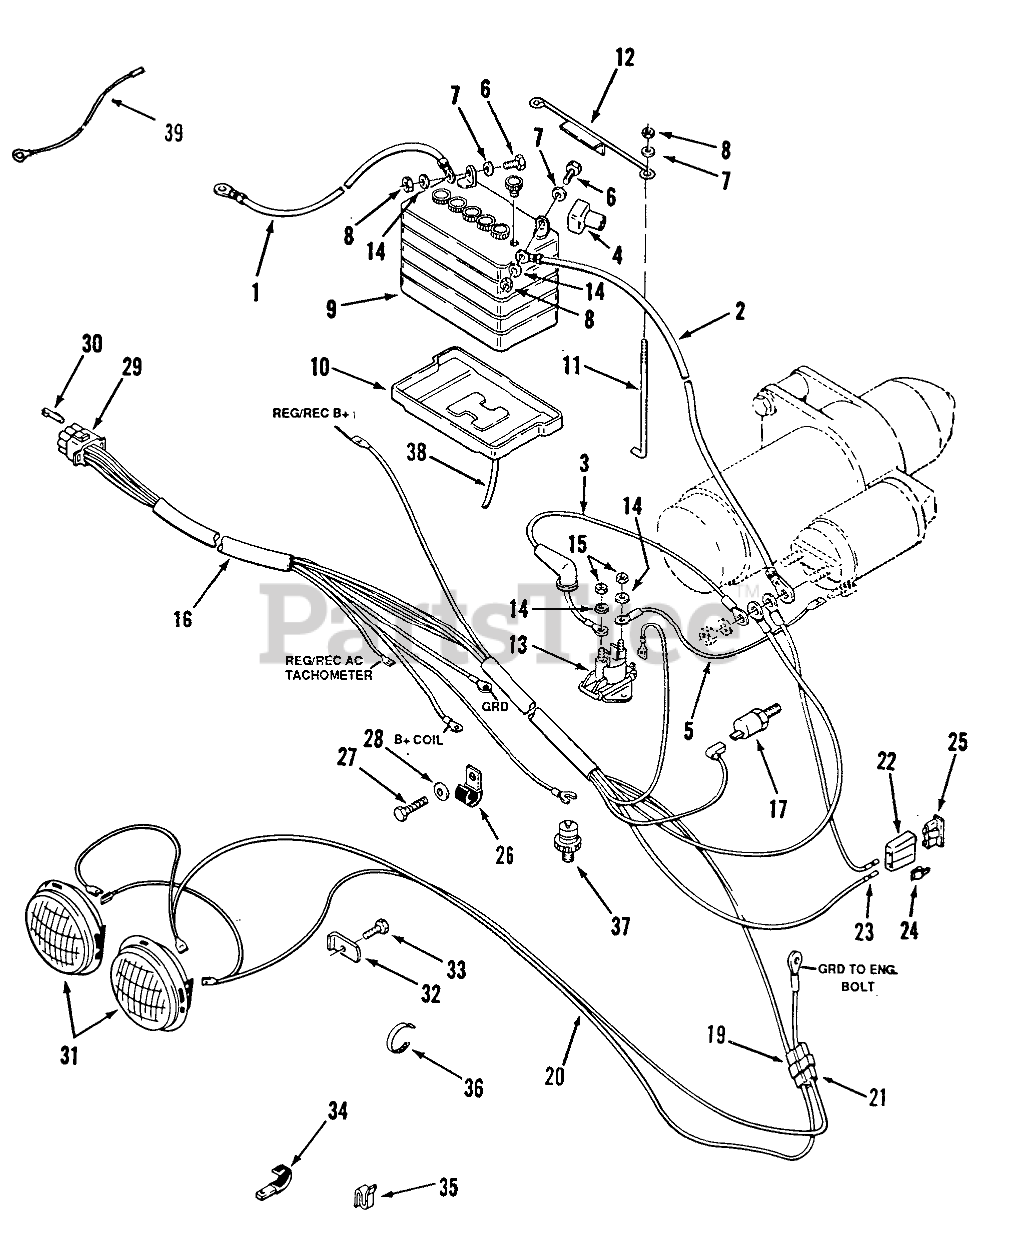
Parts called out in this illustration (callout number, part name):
1	ASS'Y-WIRE
2	ASS'Y-WIRE
3	ASS'Y-WIRE
4	Boot
5	ASS'Y-WIRE
6	Bolt
8	Nut
9	Battery
10	TRAY-BATTERY
11	HOOK-BATTERY RETAIN
12	HOLDDOWN-BATTERY
13	Solenoid
14	Washer
15	Nut
16	Engine Wiring Harness
17	HIGH TEMPERATURE
18	RECEPTACLE TERMINAL
19	MALE CONNECTOR
20	HARNESS-HEADLIGHT
21	CONNECTOR BODY
22	AUTO-FUSEBLOCK TERM
23	TERMINAL FUSE
25	FUSE-30 AMP
26	Clip
27	Bolt
28	LOCKWASHER 1/4 IT
29	CONNECTOR CAP
30	CONTACT SOCKET
31	HEADLAMP
32	LOCK-HEADLIGHT
33	Bolt
34	CLIP
35	SPEED CLIP
36	PLASTIC TIE
37	LOW OIL PRESSURE
38	TUBE-21" BATTERY DRAIN
39	ASS-Y-WIRE GROUND
53	WASHER
59	Wire-Switch to Engine
